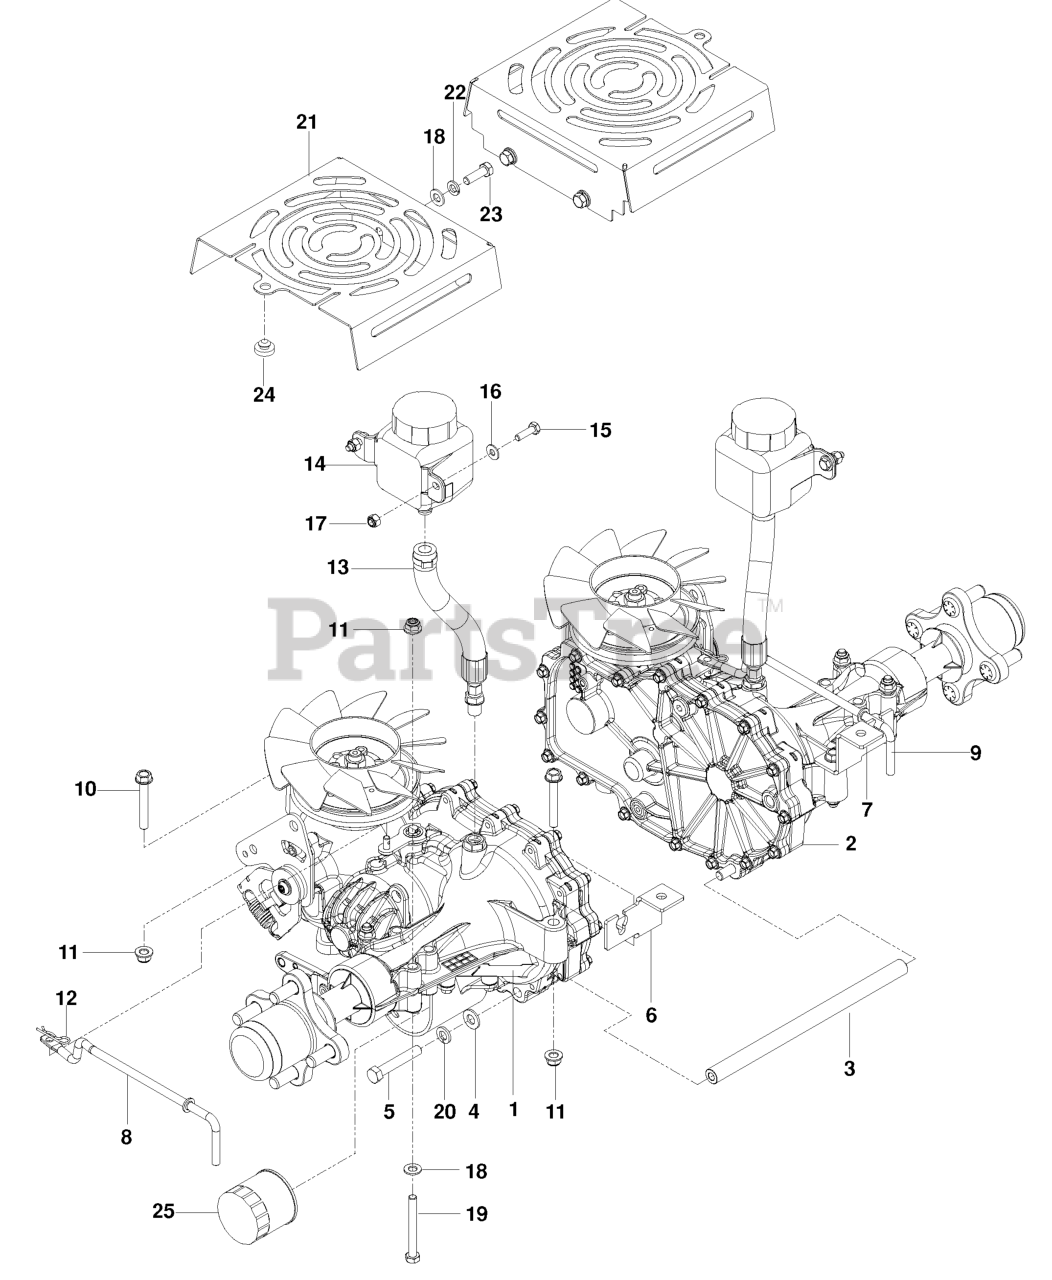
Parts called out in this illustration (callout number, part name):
1	HG_TRANS, ZT-3400, LT
2	HG_TRANS, ZT-3400, RT
3	TUBE, SPACER, 3400
4	WASHER 3/8 SAE FLAT
5	HCS 3/8-16X2-1/4 LOC PATCH GR8
6	BRACKET.TRANS.LT.BLACK
7	BRACKET, TRANS, RT BLACK
8	LINKAGE, LEFT BYPASS
9	LINKAGE, RIGHT BYPASS
10	HHFS 5/16-18 X 2.25 GD 5
11	5/16-18 NYLOC FLANGE NUT
12	HAIRPIN #2
13	HOSE ASSY, EXPANSION
14	TANK.EXPANSION.350ML 71328
15	HCS 1/4-20X7/8 GR5
16	WASHER 1/4 SAE
17	NUT.1/4-20.HEX.NYLOC.ZD
18	FLAT WASHER 5/16 SAE
19	HCS 5/16C X 2-3/4
20	SLW 3/8 STD
21	SHIELD, FAN, BLK
22	WASHER.LOCK.HVY.HLCL.SPR.5/16
23	HCS 5/16C X 1
24	GROMMET, BUMPER
25	HG_FILTER, ZT4800 52114
